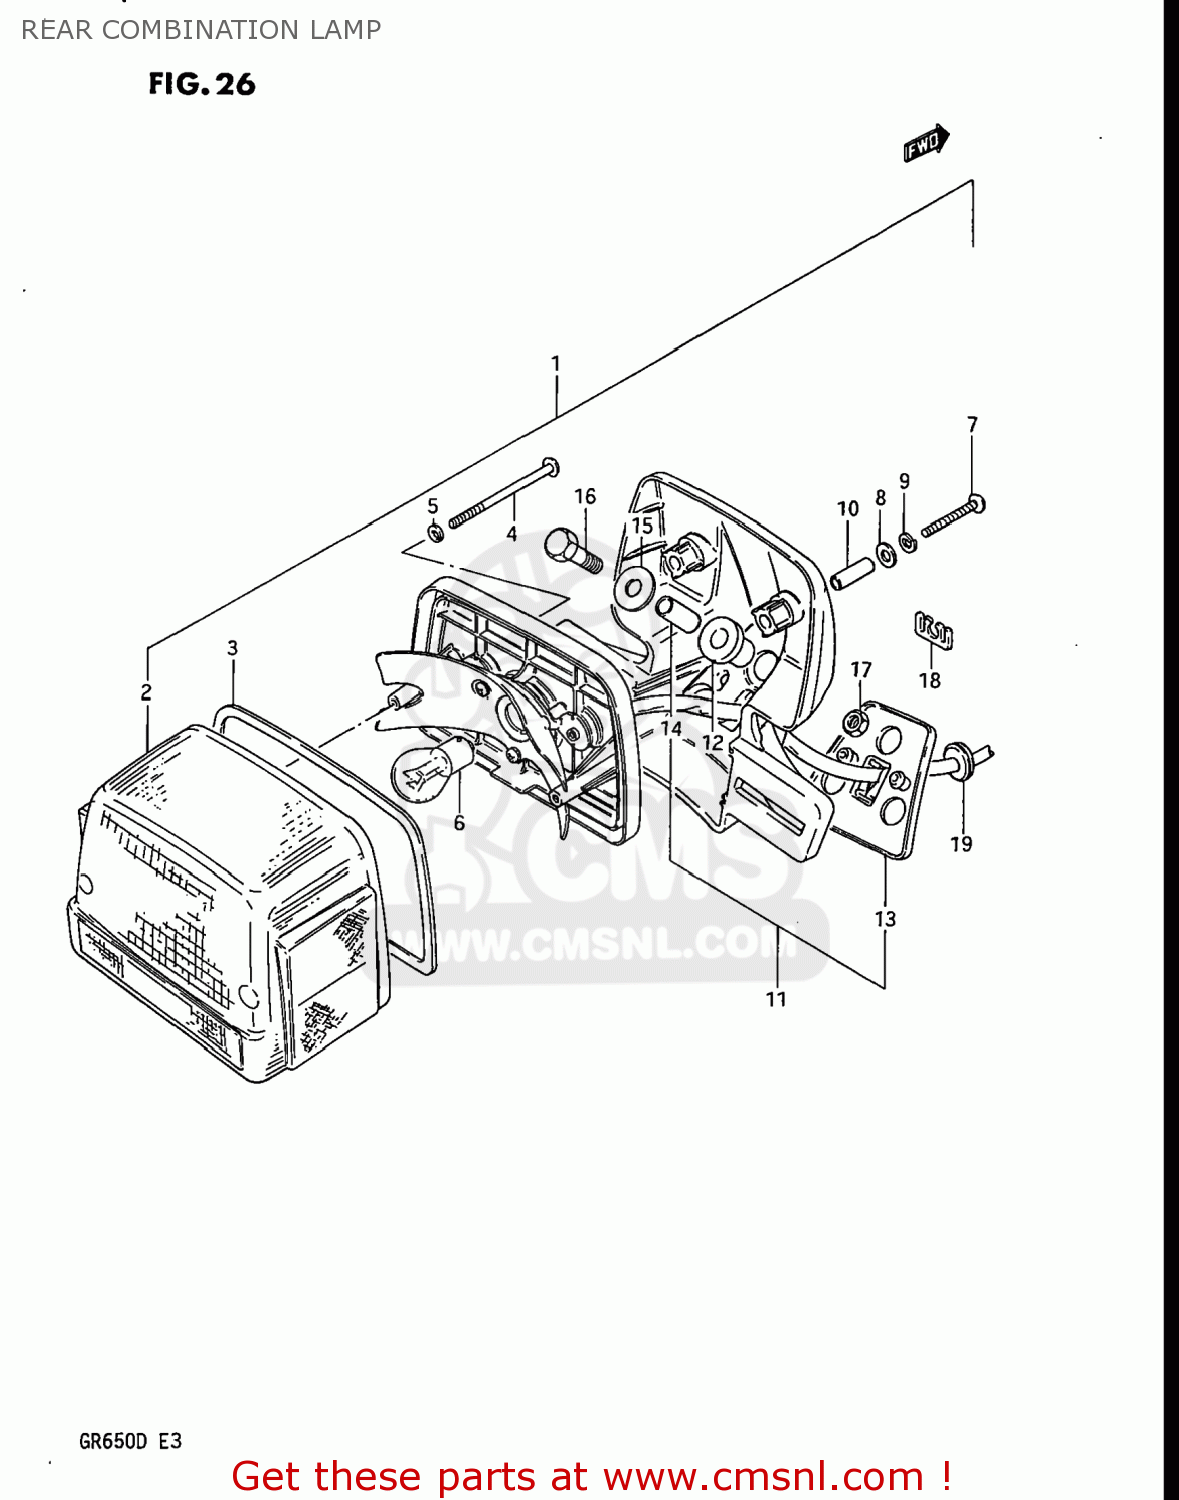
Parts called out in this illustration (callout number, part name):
1	LAMP UNIT,REAR COMBINATION
2	LENS
3	GASKET (NAS)
4	SCREW
5	GASKET (NAS)
6	BULB(12V23W)
7	SCREW
8	WASHER
9	LOCK WASHER
10	SPACER,REAR COMBINATION LAMP
11	BRACKET UNIT,TAIL LAMP
12	CUSHION,REAR COMBINATION LAMP
13	CUSHION,REAR COMBINATION LAMP
14	SPACER
15	WASHER (6.5X20X1.2)
16	BOLT
17	NUT 6MM
18	GUIDE,WIRING HARNESS
19	GROMMET
